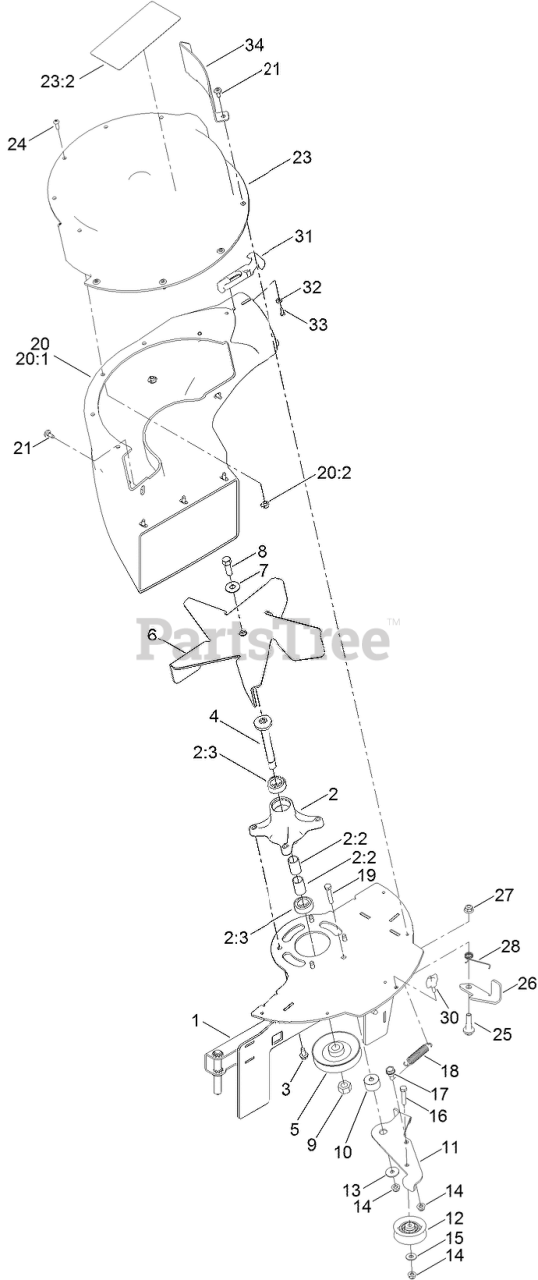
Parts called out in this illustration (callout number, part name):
1	FRAME-BLOWER
2	SPINDLE ASM
2:2	SPACER
2:3	BEARING-BALL
3	SCREW-HWHTF
4	SHAFT - SPINDLE
5	PULLEY-BLOWER
6	FAN-BLOWER
7	WASHER-BELLEVILLE
8	SCREW-HH
9	NUT-HEX
10	SPACER-ARM, IDLER
11	BLOWER-ARM, IDLER
12	PULLEY-IDLER, FLAT
13	WASHER-PIVOT
14	NUT-HF, NI
15	WASHER-FLAT
16	SCREW-HH
17	BOLT-SHOULDER
18	SPRING-RETURN, PEDAL
19	SCREW-HH
20	BLOWER CHUTE ASM
20:1	CHUTE-BLOWER
20:2	INSERT-T-NUT
21	SCREW-SHOULDER
23	BLOWER COVER ASM
23:2	DECAL-DANGER
24	SCREW-PRH
25	BOLT-SHOULDER
26	LATCH-BLOWER
27	NUT-HF, NI
28	SPRING-TORSION
31	LATCH-RUBBER
32	WASHER-FLAT
33	SCREW-PPH
34	GUARD-BLOWER
